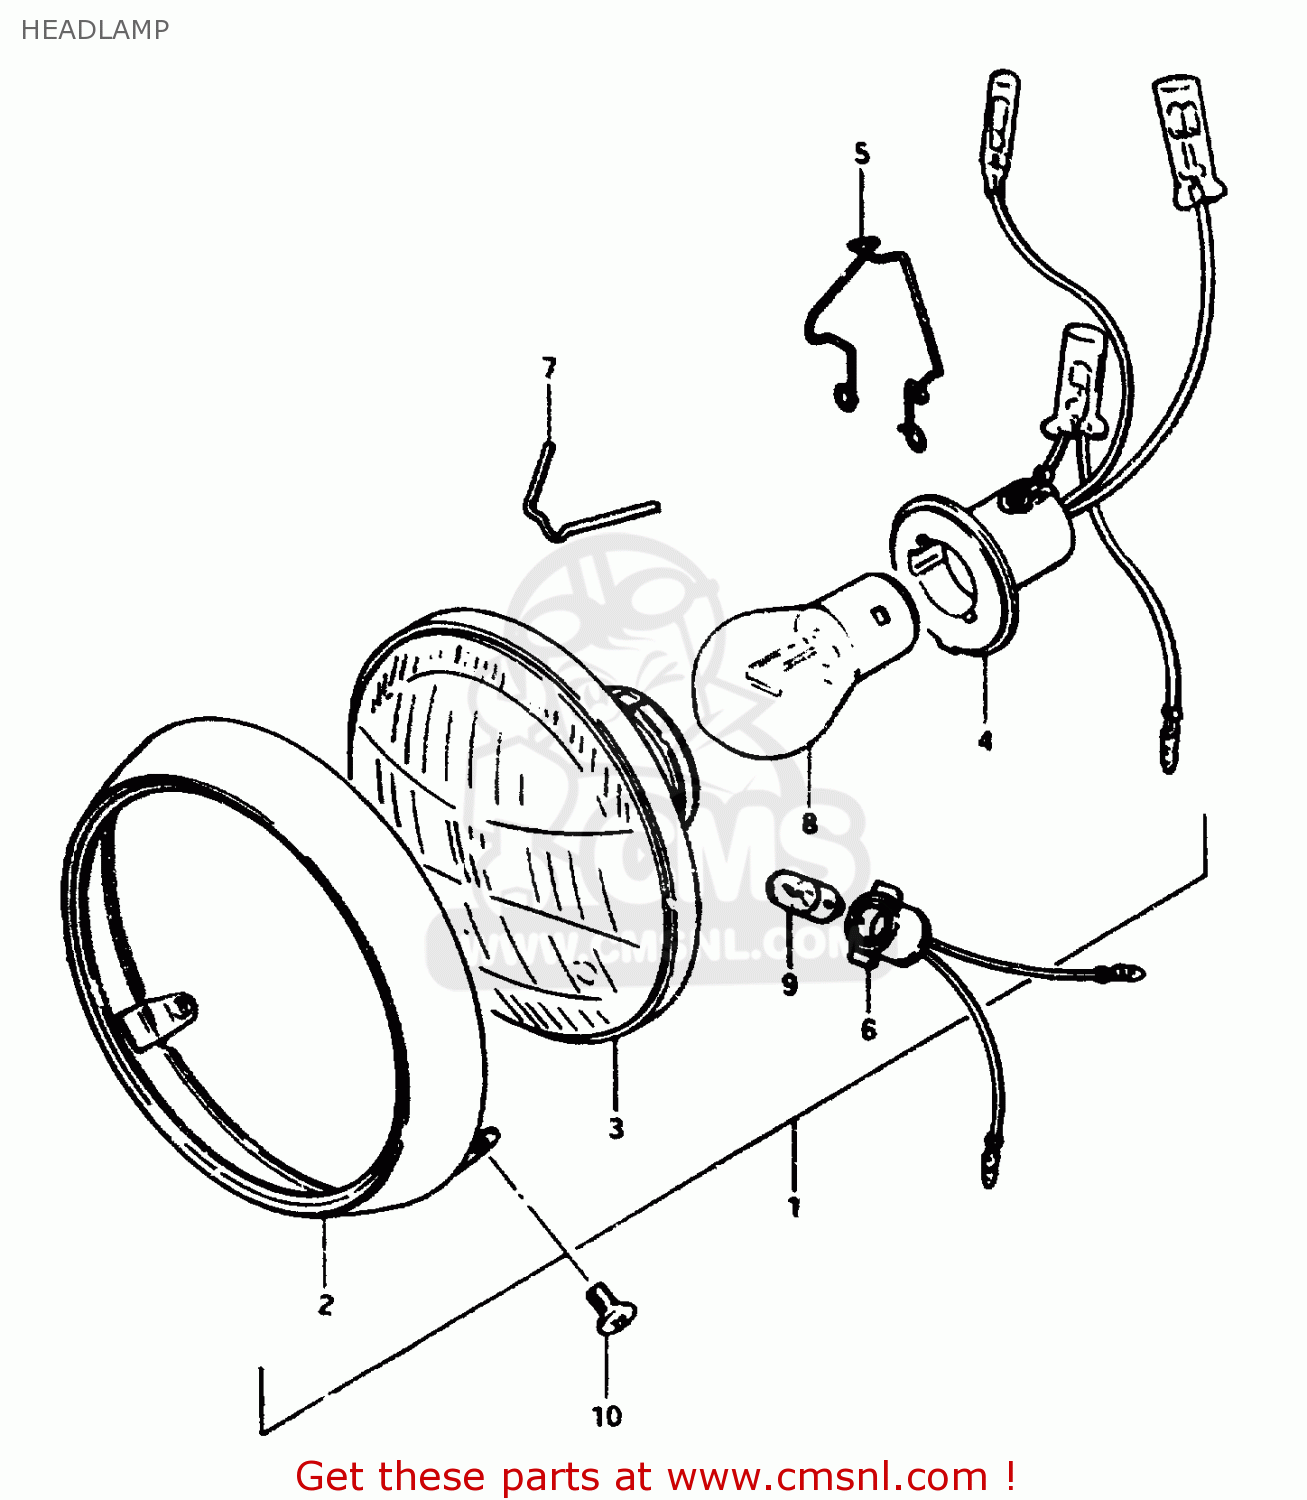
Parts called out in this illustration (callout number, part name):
1	HEADLAMP ASSY
2	RIM
3	UNIT
4	SOCKET,HEADLAMP
5	CLAMP,HEADLAMP
6	SOCKET
7	SPRING,HEAD LA
8	BULB (6V,25/25W)
9	BULB(6V4W,STANLEY,A1364J)
10	SCREW
